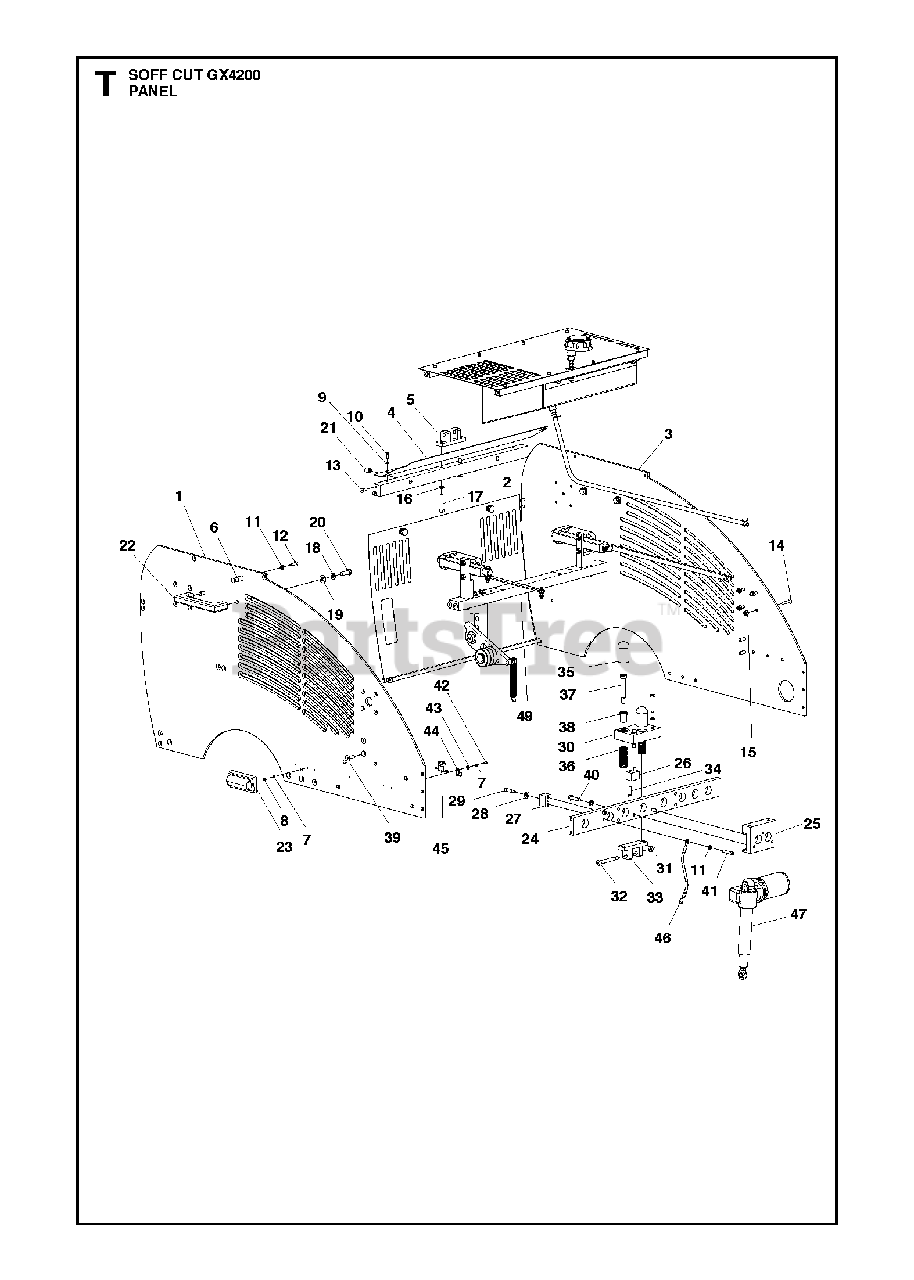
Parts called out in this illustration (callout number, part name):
15	NUT
25	FRNT WHL SPRG BLK LOWER
26	FRNT WHL SPRG BLK STOPPER
28	WASHER
30	FRNT WHL SPRG BLK UPPER
31	NUT
33	ACT. BRACKET LOWER FRONT SHOCK
